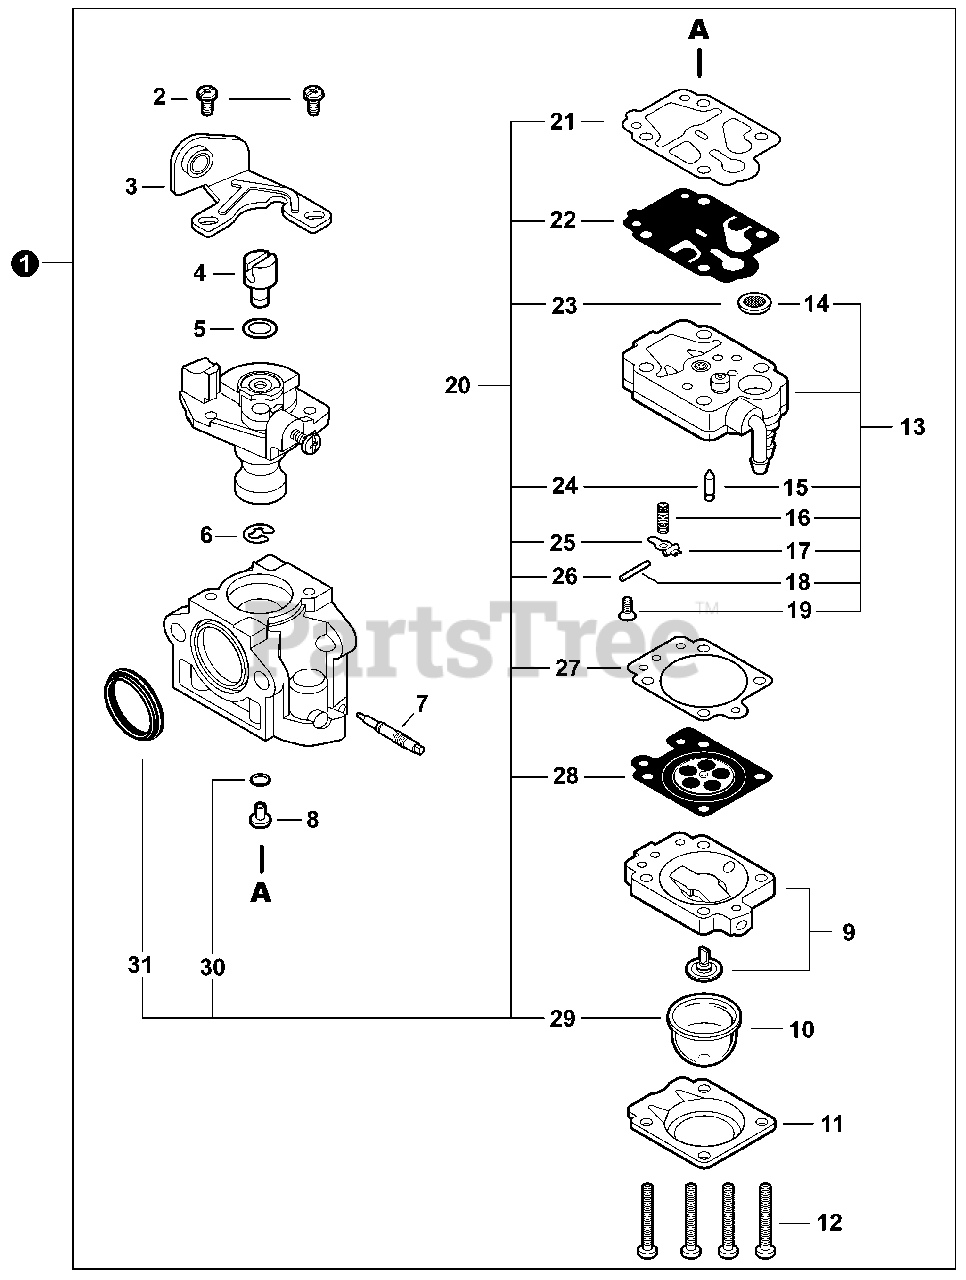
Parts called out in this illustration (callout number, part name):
1	CARBURETOR - WYK-352
3	BRACKET, THROTTLE CABLE
7	NEEDLE, HIGH SPEED
8	JET, MAIN
9	BODY ASSY, PURGE
10	BULB, PURGE
11	RETAINER, PURGE BULB
13	BODY ASSY, PUMP
14	SCREEN, FUEL INLET
15	VALVE, INLET NEEDLE
16	SPRING, METERING LEVER
17	LEVER, METERING
18	PIN, METERING LEVER
20	REPAIR KIT, CARBURETOR
21	GASKET, PUMP
22	DIAPHRAGM, PUMP
23	SCREEN, FUEL INLET
24	VALVE, INLET NEEDLE
25	LEVER, METERING
26	PIN, METERING LEVER
27	GASKET, METERING DIAPHRAGM
28	DIAPHRAGM, METERING
29	BULB, PURGE
30	O-RING
31	RING, PACKING
